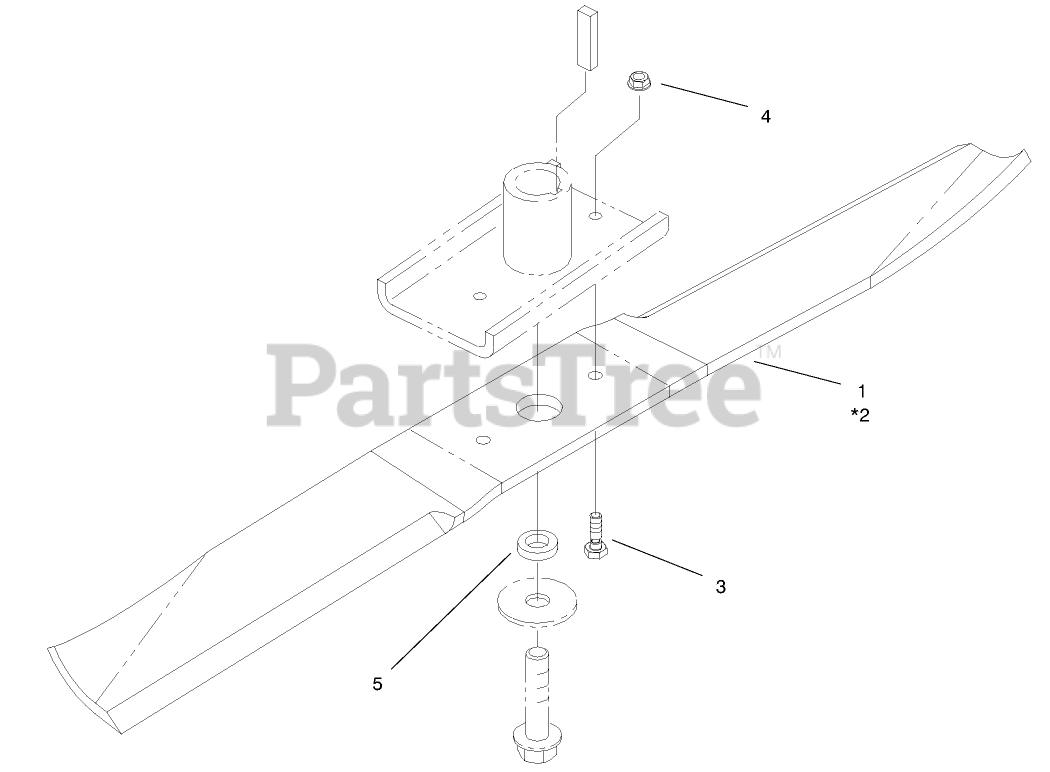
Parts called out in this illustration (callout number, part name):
1	BLADE-25IN, RH
3	BOLT-SHEAR
4	NUT-LOCK, NI
5	SPACER
